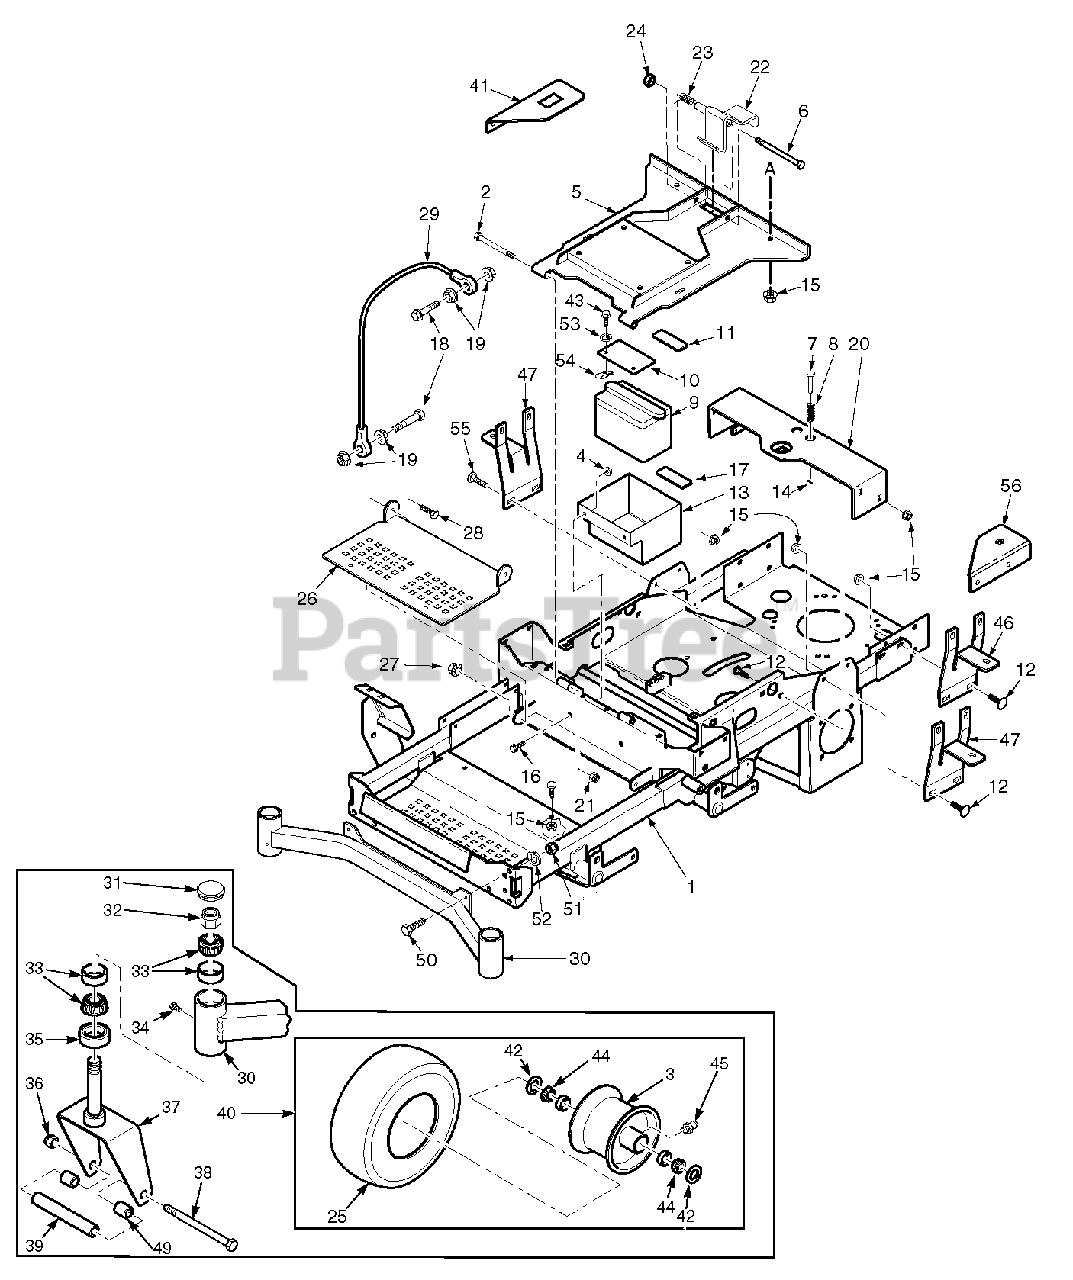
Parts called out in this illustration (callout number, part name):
1	Main Frame Assembly w/decals
2	Bolt, Hex Head 5/16-18 x 3-3/4"
3	Rim 48" & 52"
3	Rim 61"
4	Nut, Serr. Flange 3/8-16
5	Plate, Seat Mounting w/decals
6	Bolt, Hex Head 3/8-16 x 6"
7	Pin Retainer, Spring
8	Spring
9	Battery (not available through Scag)
10	Battery Cover
11	Battery Hold Down Pad
12	Bolt, Carr. 5/16-18 x 3/4"
13	Battery Box
14	Roll Pin, Spring 5/32 x 3/4"
15	Nut, Serr. Flange 5/16-18
16	Bolt, Hex Head 3/8-16 x 1"
17	Pad, Rubber
18	Bolt, Hex Head 1/4-20 x 1-1/4"
19	Nut, Serr. Flange 1/4-20
20	Seat Base Support
21	Nut, Elastic Stop 5/16-18
22	Seat Latch Weldment
23	Spring, Seat Latch
24	Locknut, 3/8-16 Center Lock
25	Tire, 13 x 5.0-6 Smooth (48" & 52")
25	Tire, 13 x 6.5-6 Smooth (61")
26	Footplate
27	Nut, Elastic Stop 3/8-16
28	Bolt, Hex Head 3/8-16 x 1"
29	Cable, Seat Stop
30	Weldment, Caster Support (48" & 52")
30	Weldment, Caster Support (61")
31	Cap, Grease
32	Nut, Elastic Stop 1.0"-14
33	Bearing Set
34	Plug, 1/4-28
35	Seal, 2.0" OD x 1.625" ID
36	Nut, Elastic Stop 1/2-13
37	Yoke, Front Caster Wheel
37	Yoke, Front Caster Wheel (61")
38	Bolt, Hex Head 1/2-13 x 7-1/2"
38	Bolt, Hex Head 1/2-13 x 9-1/2" (61")
39	Sleeve - 48" & 52"
39	Sleeve - 61"
40	Caster Wheel Assembly
40	Caster Wheel Assembly (61")
41	Bracket, Hour Meter
41	Bracket, Hour Meter - Fuel Valve (EFI Only)
43	Bolt, Hex Head 3/8-16 x 1-1/4"
44	Roller Bearing
45	Fitting, Grease
46	Mounting Bracket, Oil Tank
47	Mounting Bracket, Fuel Tank
48	Seat Pan
49	Spacer, Caster Wheel
50	Bolt, Hex Head 7/16-14 x 1-1/4"
51	Nut, Elastic Stop 7/16-14
52	Lockwasher, 7/16"
53	Lockwasher. 3/8" Spring
54	U-Nut, 3/8-16
55	Bolt, Carriage 5/16-18 x 1"
56	Bracket, Fuel Valve (not used on EFI)
